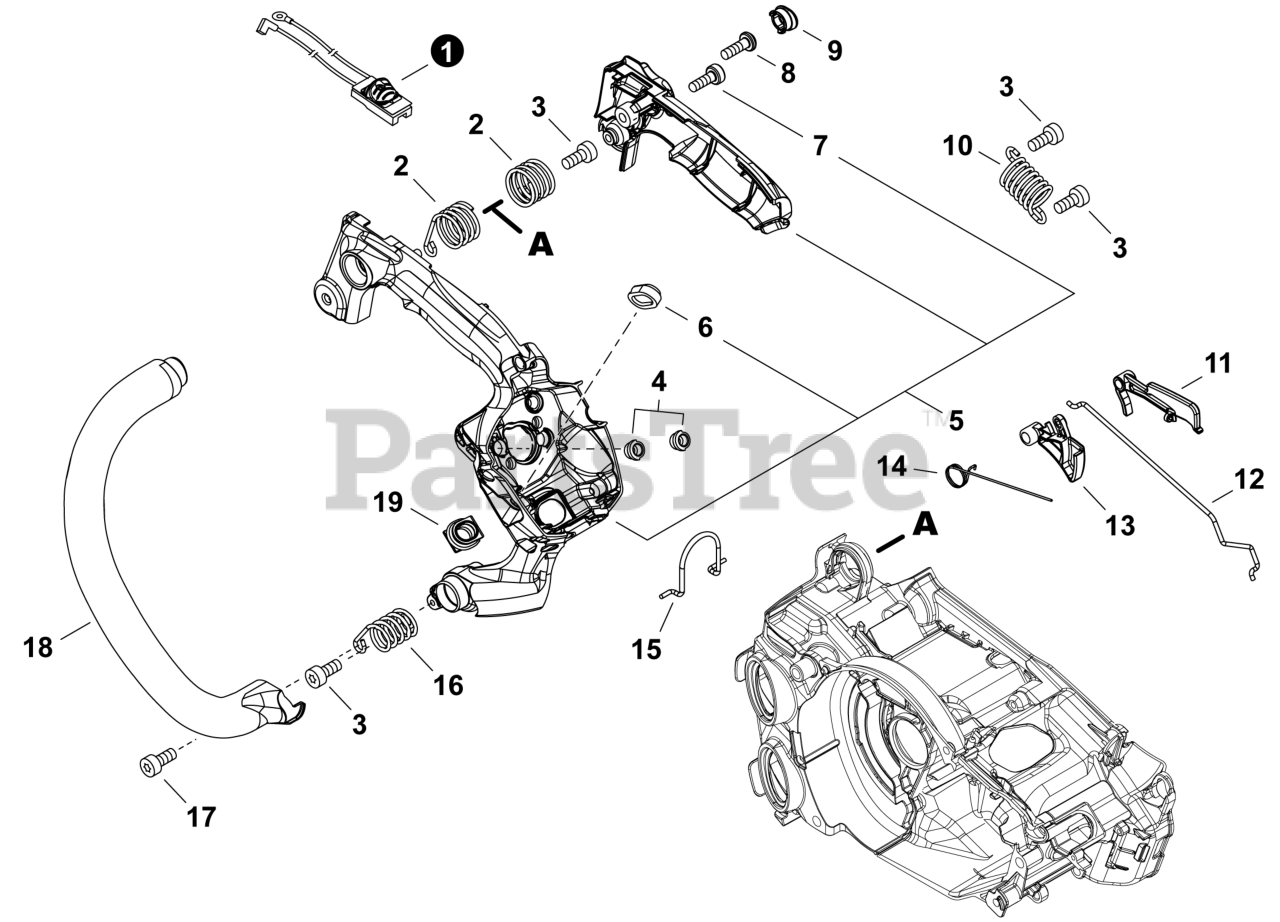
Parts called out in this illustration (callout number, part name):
1	SWITCH, ON-OFF
2	SPRING, COMPRESSION
3	BOLT, TORX 4x12
5	HANDLE SET, REAR
6	GROMMET, NEEDLE
7	BOLT, TORX 4x16
8	BOLT, TORX 5x16
10	SPRING, COMPRESSION
11	LOCKOUT, THROTTLE
12	ROD, THROTTLE
13	TRIGGER, THROTTLE
14	SPRING, TORSION
15	RING, HARNESS
16	SPRING, COMPRESSION
17	BOLT, TORX 4x16
18	HANDLE, FRONT
19	PIPE, INTAKE
